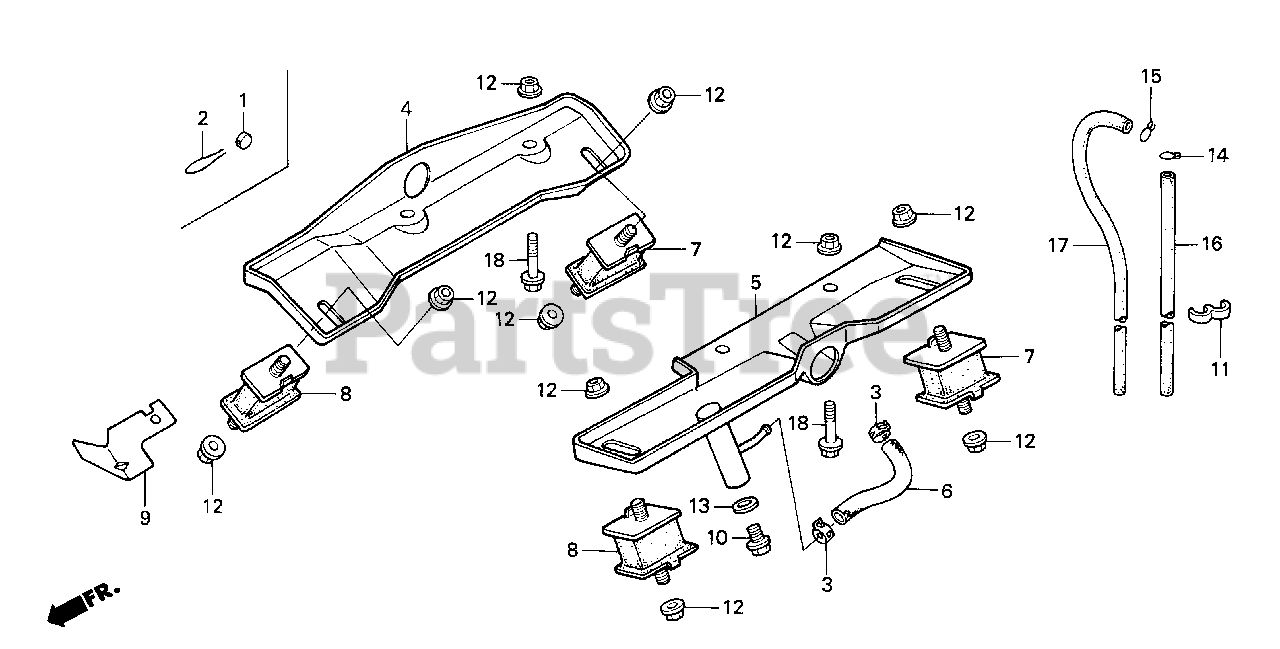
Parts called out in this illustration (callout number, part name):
2	WIRE, LOCK
3	CLAMP, MASTER CYLINDER OIL HOSE
4	PLATE, R. ENGINE MOUNTING
5	PLATE, L. ENGINE MOUNTING
6	TUBE, OIL DRAIN
7	RUBBER, RR. ENGINE MOUNTING
8	RUBBER, ENGINE MOUNTING
9	COVER, PULLEY
10	BOLT, DRAIN PLUG
11	CLIP, HIGH TENSION CORD
12	NUT, FLANGE (10MM)
13	WASHER, DRAIN PLUG (12MM)
14	CLIP, TUBE (C8)
15	CLIP, TUBE (C9)
16	BULK HOSE, VINYL (4.5X8X3000)
17	BULK HOSE, VINYL (5X9X8000)
18	BOLT, FLANGE (10X40)
